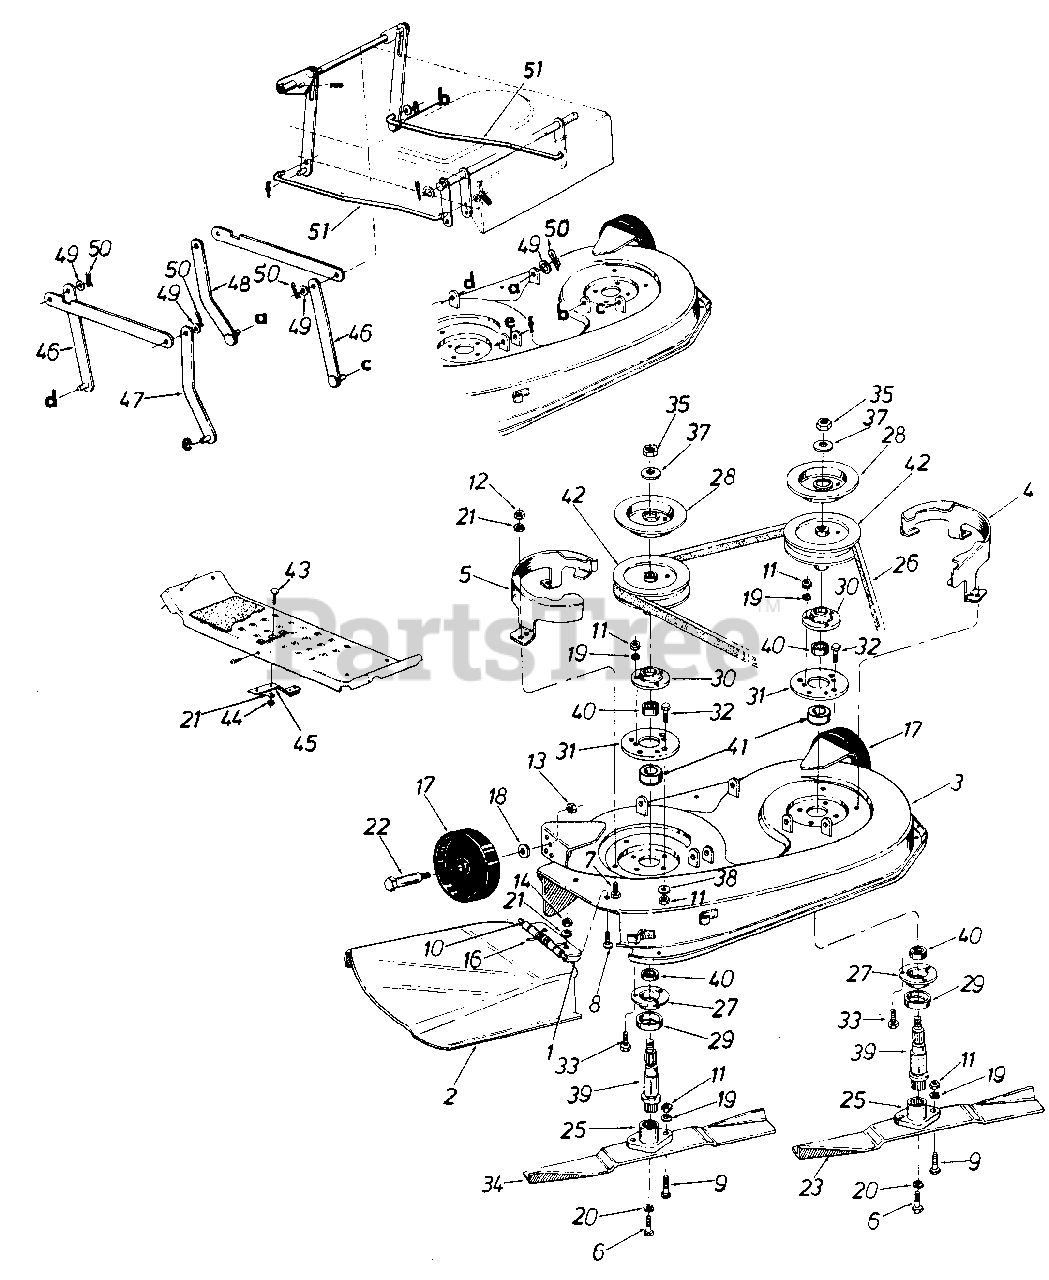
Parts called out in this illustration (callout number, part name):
1	Chute Bracket
2	Chute Deflector
3	38" Deep Deck Ass'y.
6	Hex Bolt 3/8-24 x 1.00"
7	Hex BOlt 1/4-28 x .62"
8	Truss Mach. Scr. 1/4-20 x .75"
9	IHex Scr. Special 5/16-24 x 1 .0"
10	Hinge Pin
11	Hex Nut 5/16-24 Thd.
12	Hex Nut l/4-28 Thd.
13	Hex Top L-Nut 3/8-16 Thd.
14	Hex Jam Nut 1/4-20 Thd.
16	Torsion Spring
17	Deck Wheel-5"
18	Bell-Wash. .40" I.D. x .88" O.D.
19	L-Wash. 5/16" I.D.
20	L-Wash. 3/8" I.D.-H.D.
21	L-Wash. 1/4" I.D.
22	Shld. Bolt .498" Dia. x 1.53"
23	High-Lift Blade-L.H.
25	Blade Adapter
26	5L V-Belt
27	Bearing Housing 1.85" I.D.
28	Brake Disc
29	Bearing Shield
30	Open Brg. Housing 1.85" I.D.
31	Spindle Mounting Plate
32	Hex Bolt 5/16-24 x .75"
33	Hex Bolt Special 5/16-24 x 1.O"
34	High-Lift Blade-R.H.
35	Hex Jam Nut 5/8-18 Thd.
37	L-Wash. 5/8" I.D.
38	Bell-Wash. .345" I.D. x .88" O.D.
39	Blade Spindle
40	Ball Brg. .787" I.D. x 1.85" O.D.
41	Spacer 1.0" O.D. x .790" I.D. x .350"
42	5" Dia. Pulley
43	Carr. Bolt 1/4-20 x .62"
44	Hex Nut 1/4-20 Thd.*
45	Blade Brake Ass'y*
46	Link Deck Hanger Ass'y.
47	Link Deck Hanger Ass'y.
50	Inter. Cotter Pin .50" Dia.
51	Stabilizer Rod
